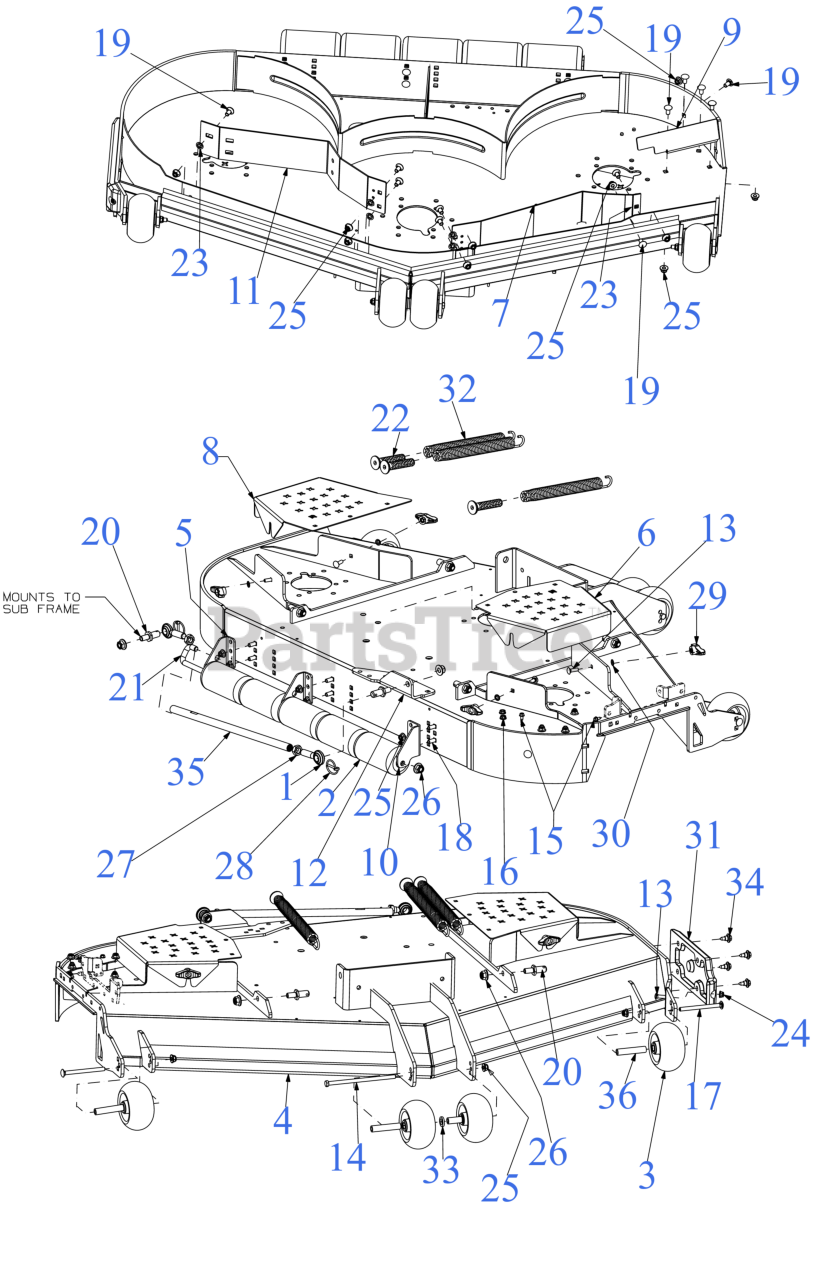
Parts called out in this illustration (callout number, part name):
1	MALE ROD END
2	ROLLER ASSEMBLY
3	5" DIA DECK WHEEL COMPLETE
4	60" FAB DECK SHELL
5	REAR MOUNT BRACKET
6	DECK BELT COVER
7	DECK BAFFLE
8	BELT COVER
10	REAR ROLLER BRACKET (RH)
11	DECK BAFFLE
12	DECK BELT GUIDE BRACKET
13	CARRIAGE BOLT 5/16-18 x 1.00
14	SCREW 3/8-16 x 7.25 GR5
15	SCREW 1/4-20 X.500
16	SCREW 5/16-18 x .500
17	CARRIAGE BOLT 3/8-16 x 4.25 GR5
18	CARRIAGE BOLT 3/8-16 x 1.00 GR5
19	CARRIAGE BOLT 3/8-16 x .75
21	REAR ROLLER PIN
22	SPRING INSERT SCREW
24	FLANGE LOCK NUT 5/16-18
27	HEX JAM NUT 5/8-18
28	LYNCH PIN .1875
29	WING KNOB 5/16-18
31	DECK SKID PLATE (LH)
32	EXTENTION SPRING 1.20 x 11.35
33	FLAT WASHER .632X1.00X.16
34	SHOULDER SCREW .43X.29X5/16-18 TT
35	TUBE .565 X .750 X 18.75"LG
36	WHEEL SPACER .38ID x 3.04LG
